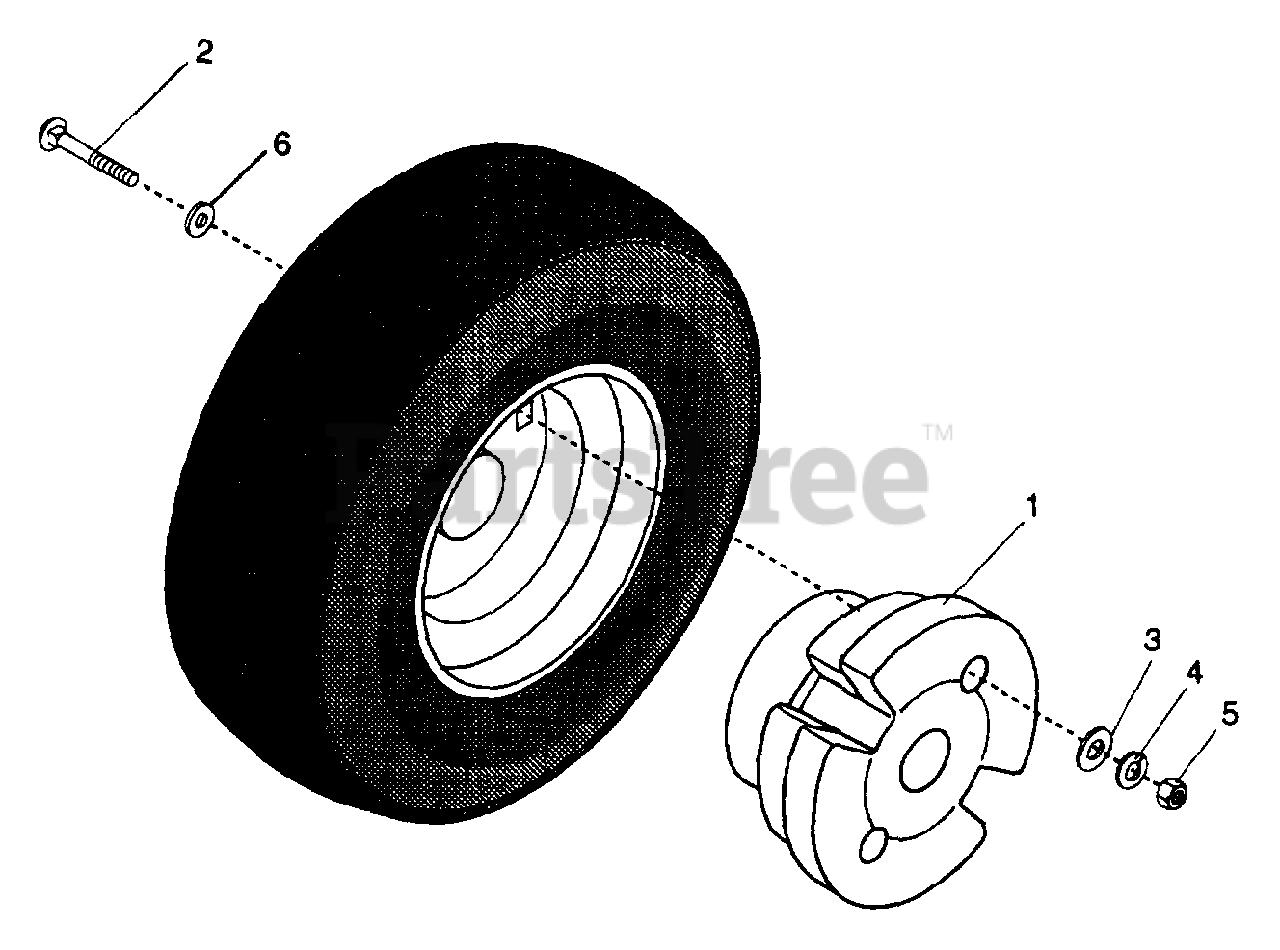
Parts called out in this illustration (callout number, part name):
1	WHEEL WEIGHT 75 LB.
2	BLT-RDHDSQNK .50-13X9.00 YWZC
3	WSHR-FL-STL .531X1.062X.095 PL
4	WSHR-LK .500X.151 HVY PL
5	NUT .50-13 PL
6	GROMMET .438ID X .688 OD
